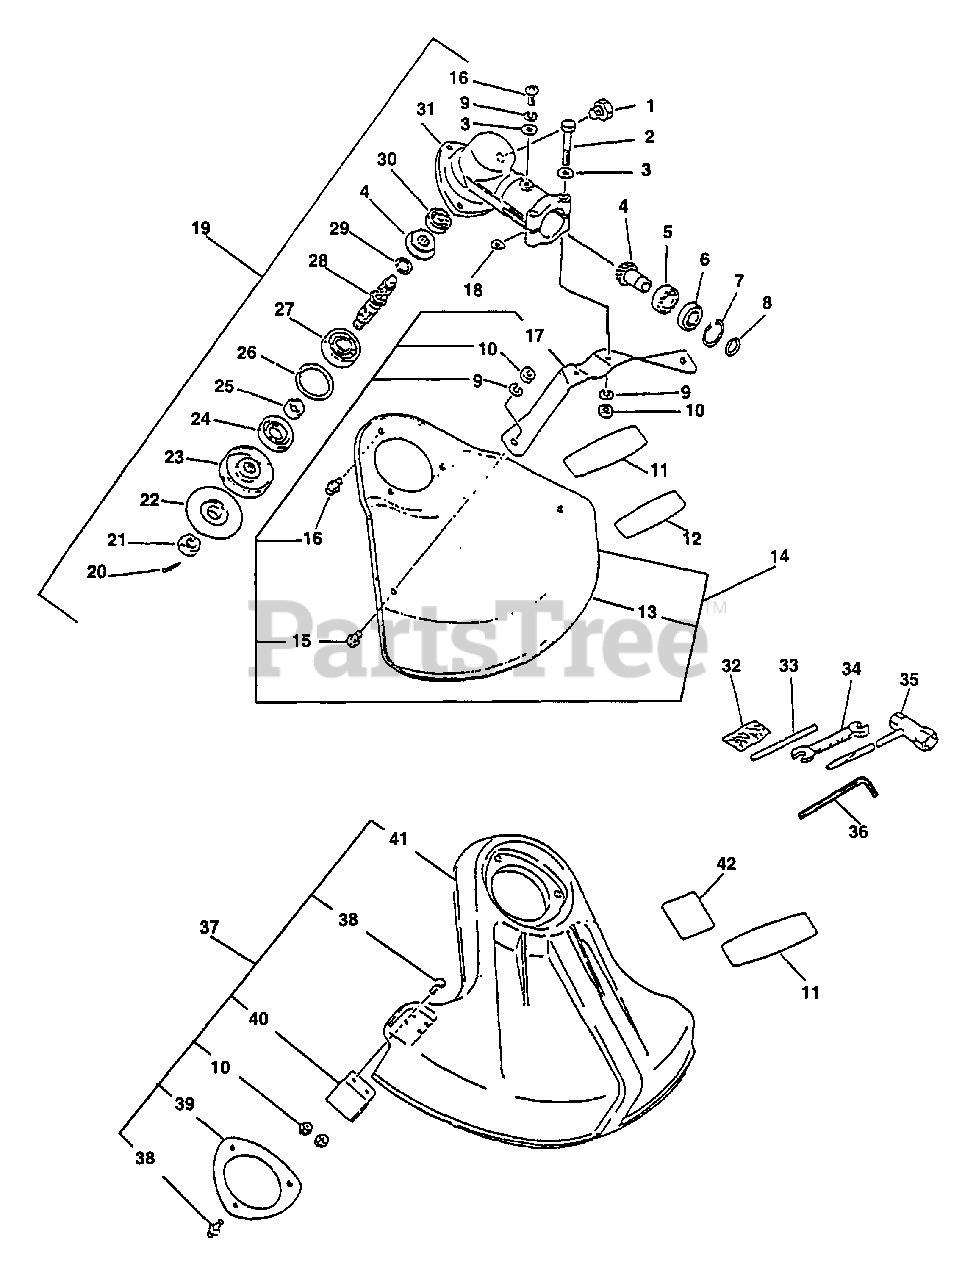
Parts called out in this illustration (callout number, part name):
1	BOLT - 8X8
1	BOLT - 8X6
2	BOLT - 5X35
3	WASHER - 5
4	GEAR SET - BEVEL
5	BEARING, BALL - 6900
6	BEARING, BALL - 6900Z
7	RING, RETAINING - 22
8	RING, RETAINING - 12
9	LOCKWASHER - 5
11	LABEL - ECHO
12	LABEL - DANGER
13	SHIELD, DEBRIS - METAL
14	DEBRIS SHIELD KIT - METAL
15	SCREW - 5X8
16	SCREW - 5X10
17	BRACKET, SHIELD
19	GEAR CASE ASSY
20	PIN, SPLIT - 2X22
21	NUT - 10 -- LEFT HAND
22	ADAPTOR, BLADE - LOWER
23	ADAPTOR, BLADE - UPPER
24	SEAL, OIL
26	RING, RETAINING - 32
27	BEARING, BALL - 6201
28	GEAR - SHAFT
29	RING, RETAINING - 10
30	BEARING, BALL - 609
31	CASE, GEAR
32	PIN, SPLIT - 2X22
33	LOCKING TOOL
34	SPANNER - 8X10mm
35	T-WRENCH - 17X19mm
36	HEX KEY - 3mm
37	DEBRIS SHIELD KIT
38	SCREW - 5X16
39	PLATE, SHIELD
40	KNIFE, TRIMMER LINE
41	SHIELD, DEBRIS - PLASTIC
42	LABEL - CAUTION
